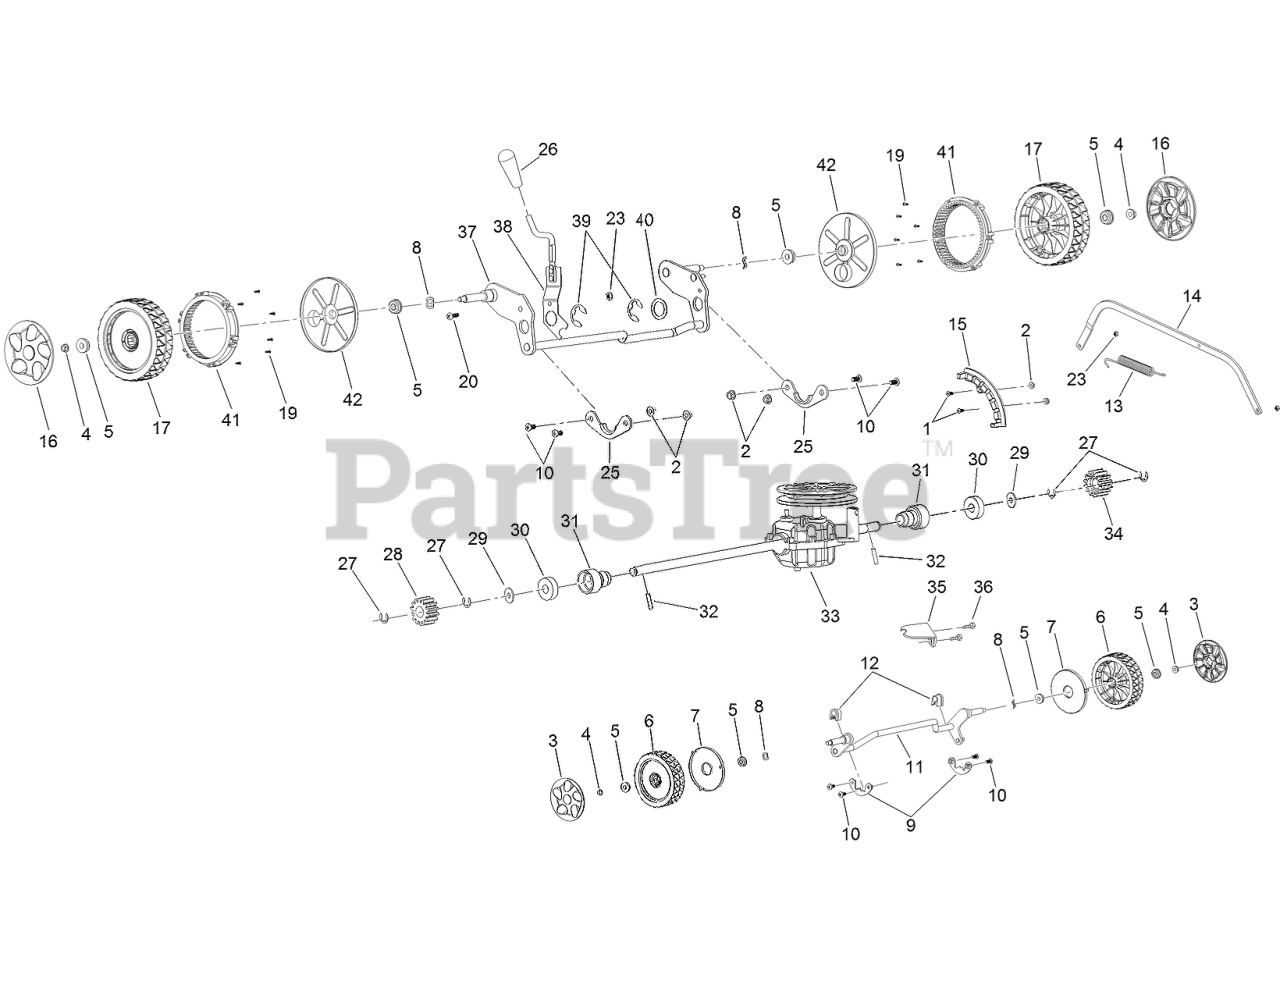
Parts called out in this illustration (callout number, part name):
1	SCREW-TOOTH
2	NUT-LOCK, FLANGE
3	CAP-HUB (7)
4	NUT-LOCK, FLANGE
5	BEARING
6	WHEEL ASM (7)
7	COVER-WHEEL, DUSTPROOF
8	WASHER-WAVE
9	CLAMP-AXLE, FIXED
10	SCREW-TOOTH
11	FRONT WHEEL AXIS ASM
12	RING-FIXED
13	SPRING-TENSION
14	BRACKET-CONNECTING, HOC
15	BOARD-ADJUSTER, HOC
16	CAP-HUB (8)
17	WHEEL ASM (8)
19	SCREW-SELF DRIVING
20	SCREW-PAN, CROSS
23	NUT-LOCK
25	RING-FIXED
26	HANDLE-LEVER, HOC
27	WASHER-SPRING
28	GEAR OUTPUT ASM-RH
29	WASHER-FLAT
30	BEARING
31	SHEATH-BEARING
32	PIN-CYNLINDRICAL
33	GEARBOX
34	GEAR OUTPUT ASM-LH
35	BRACKET-LOCATION
36	BOLT-HH, FLANGE
37	REAR AXLE SHAFT ASM
38	HANDLE ASM
39	WASHER-SPRING
40	WASHER
41	GEAR RING
42	COVER-WHEEL, DUSTPROOF
